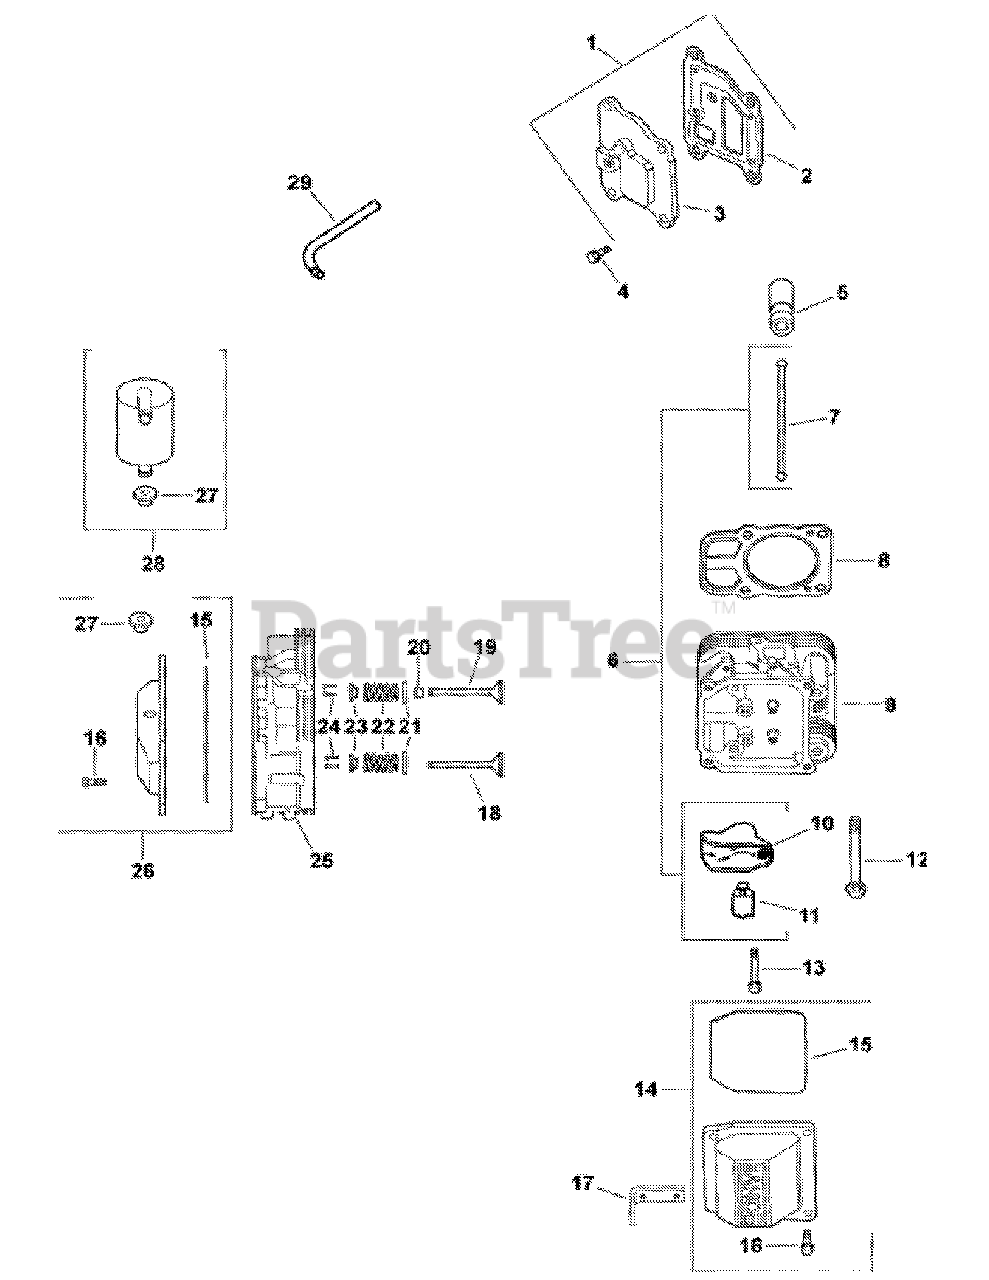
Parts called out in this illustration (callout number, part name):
1	Breather Cover Kit
2	Breather Gasket
3	Breather Cover
4	Hex Flange Screw
5	Valve Lifter
6	Valve Train Kit
8	Head Gasket
9	Head Assembly #1 Cylinder
11	Rocker Arm Pivot
12	Hex Flange Screw
13	Hex Flange Screw
14	Valve Cover Kit, Plain
15	O-Ring
16	Hex Flange Screw
17	Lifting Strap
18	Exhaust Valve (Std.)
18	Exhaust Valve (.25)
19	Intake Valve (Std.)
19	Intake Valve (.25)
20	Valve Stem Seal
21	Spring Retainer
22	Valve Spring
23	Valve Spring Cap
24	Retainer Kit
25	Head Assembly #2 Cylinder
26	Valve Cover Kit, Breather
27	Rubber Grommet
28	Breather Separator Kit
29	Breather Hose
